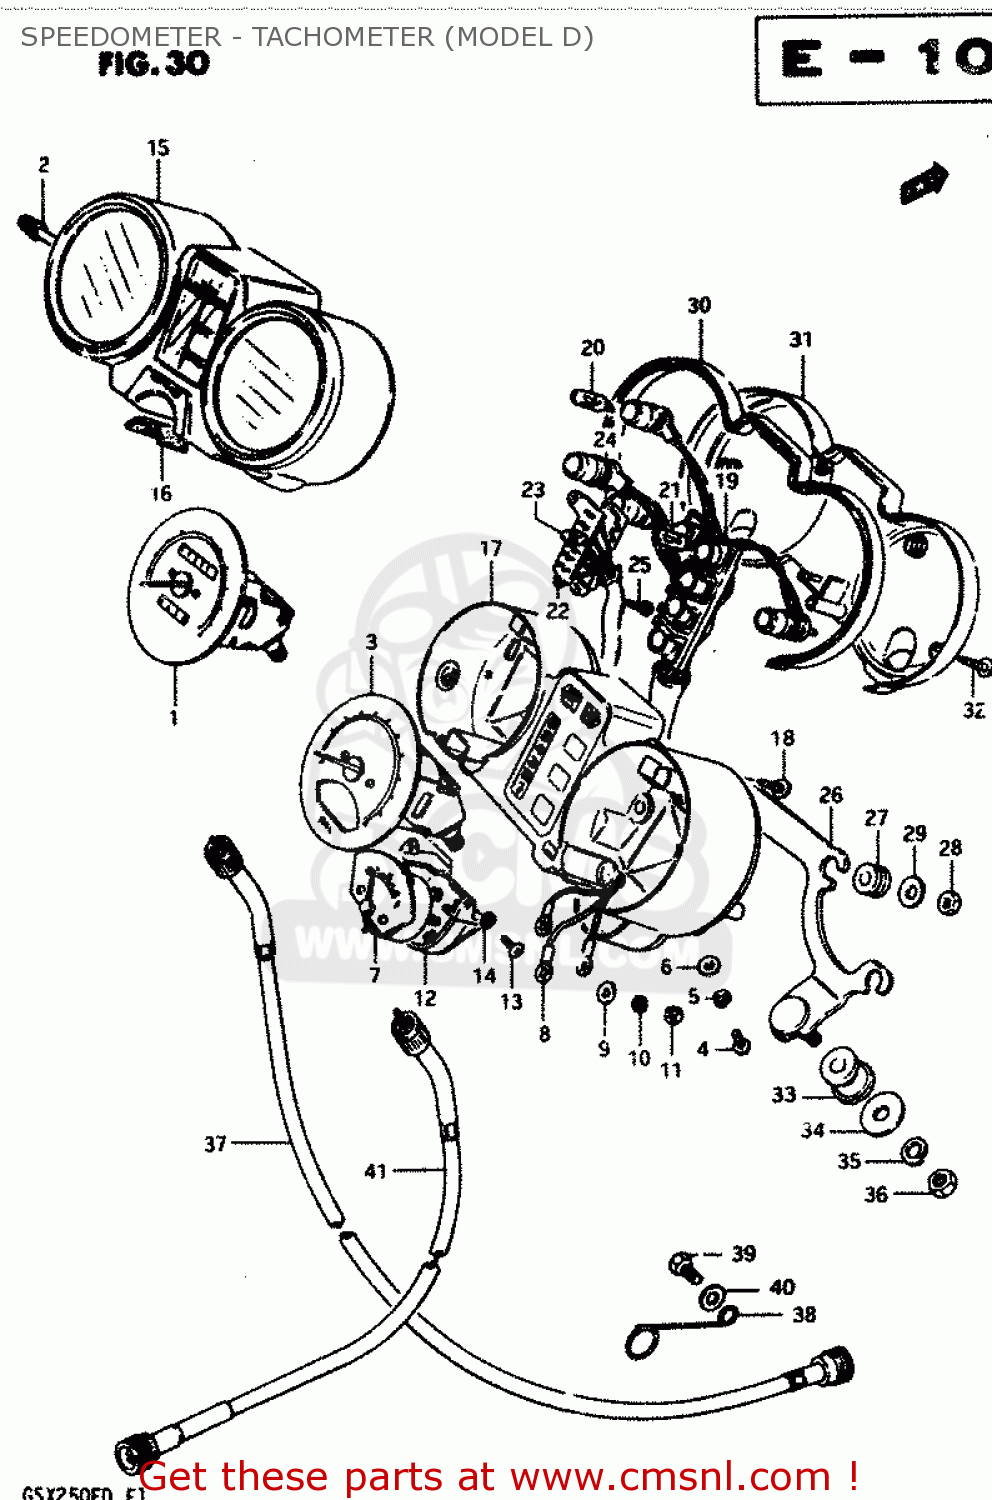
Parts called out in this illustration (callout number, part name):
1	SPEEDOMETER (KILO)
2	KNOB
3	TACHMETER
4	SCREW 4X10
5	WASHER
6	LOCK WASHER
7	METER,FUEL
8	WIRE,FUEL METER LEAD
9	WASHER,FUEL METER
10	LOCK WASHER
11	NUT 3MM
12	BRACKET,FUEL METER
13	SCREW
14	LOCK WASHER
15	HOOD,METER
16	SEAL,IGNITION SWITCH
17	CASE,METER,INNER
18	SCREW
19	SOCKET
20	BULB(12V3.4W,T10)
21	BULB(12V1.7W,T10,WB121)
22	SOCKET,GEAR INDICATOR
23	BULB(14V1.12W,BQ041-32503B)
24	COVER,INDICATOR,LOWER
25	SCREW
26	BRACKET,COMBINATION METER
27	CUSHION,METER
28	NUT
29	WASHER (5.5X16X1.2)
30	COVER,METER,UNDER
31	COVER,LWR
32	SCREW
33	CUSHION,METER BRACKET
34	WASHER (8.5X20X1.6)
35	LOCK WASHER
36	NUT
37	CABLE ASSY,SPEEDOMETER
38	CLAMP,SPEEDOMETER CABLE
39	BOLT, UPPER
40	WASHER
41	CABLE ASSEMBLY,TACHOMETER
